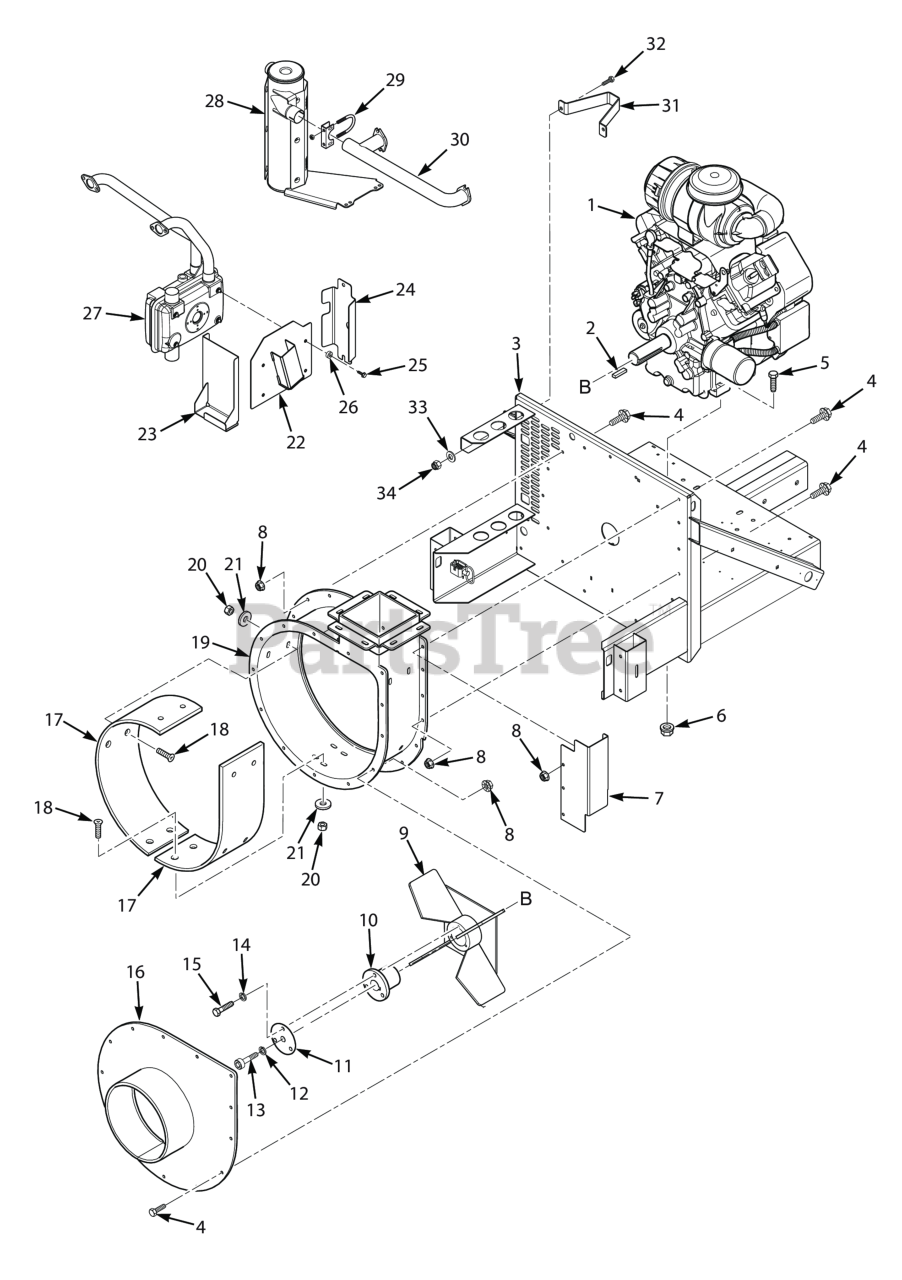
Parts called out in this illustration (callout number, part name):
1	Engine, 29HP Briggs & Stratton Vanguard
1	Engine, 26.5hp Kohler EFI (not available through Scag Power Equipment)
2	Key, 3/8 x 3/8 x 3-1/2"
3	Base & Frame Weldment w / Decals
4	Bolt, Hex Head Serrated Flange 3/8-16 x 3/4"
5	Bolt, Hex Head 5/16-18 x 1-1/2" - Front
5	Bolt, Hex Head 5/16-18 x 2-1/2" (x3) (35BV & 37BV-EFI)
6	Nut, Serrated Flange 5/16-18 (Right Front Engine Mounting, Briggs and Kohler Only)
7	Bracket, Hose Protector
8	NUT, 3/8-16 SERRATED FLANGE HEX HEAD
9	Impeller Weldment, TL20W
10	Hub, Tapered Locking Q2 x 1-7/16"
11	Cover Plate, Hub Taper - TL20W
12	Lockwasher, 5/8" Spring
13	Socket Head Cap Screw, 5/8-18 x 1-3/4"
14	Lockwasher, 3/8" Spring, Kawasaki FX / FS
15	Bolt, Hex Head 3/8-16 x 1-3/4" (Kohler EFI)
16	Cover, Housing - TL20W
17	Wearliner Kit w/ Hardware
18	Capscrew, 3/8-16 x 1-1/4"
19	Housing Weldment w / Decals
20	HEX LOCKNUT, ELASTIC STOP, 3/8-16
21	Flatwasher, 1/2 (.5/6 x .938 x .105)
22	Weldment, Exhaust Deflector - 26.5hp Kohler EFI
23	Heatshield, Front
24	Heatshield, Rear
25	Bolt, Hex Head Cap Screw M5-.8 x 10 Flanged
26	Spacer
27	Muffler, Kohler EFI (order through engine manufacturer)
28	Muffler, 29hp Briggs & Stratton
29	Clamp, Muffler (Clamp Only)
30	Exhaust Manifold, 29hp Briggs & Stratton
31	Muffler Guard
32	Bolt, Hex Head, 3/8-16 x 1 Gr. 5
33	Flatwasher, 3/8" Special (.391 x .938 x .105)
34	HEX NUT, ELASTIC STOP LOCK, 3/8-16
